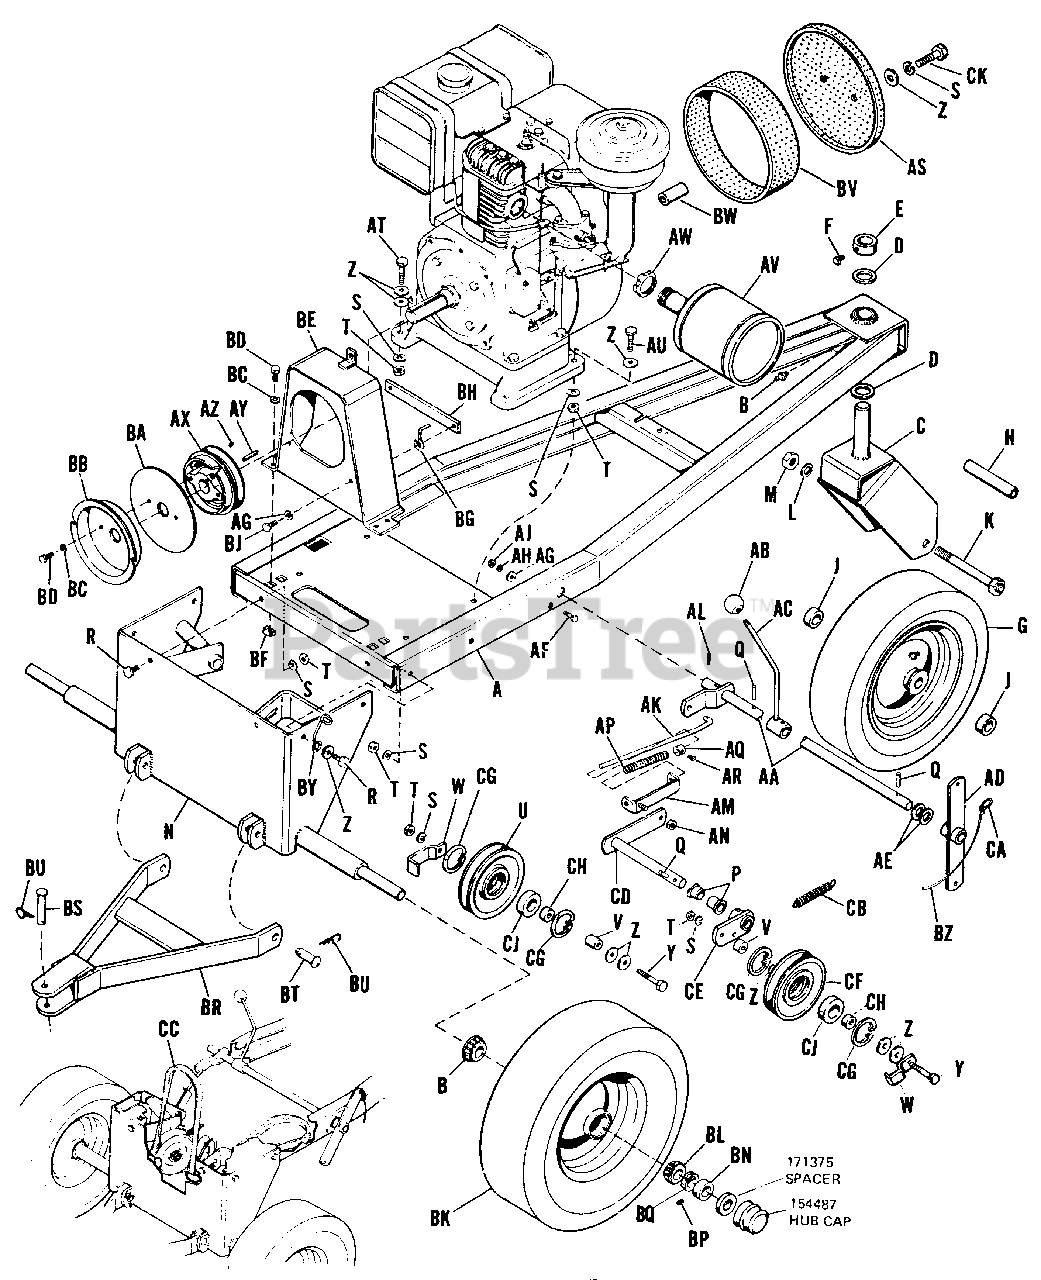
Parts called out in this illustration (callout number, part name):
A	Frame Assembly
B	Crease Fitting
C	Caster Assembly
E	Set Collar
F	Set Screw 5/16-18 x 1/2" lg.
G	Wheel & Tire Assembly
H	Spacer Tube
K	Rear Axle Shaft
L	Lock Washer 1/2"
M	Hex Nut Full 1/2-13
N	Front Plate Assembly
P	Clutch Bushing
R	Hex Capscrew 3/8-16 x 3/4" lg.
S	Lock 3/8" Washer 3/8"
T	Hex Nut Full 3/8-16
U	Idle Pulley
W	Belt Guide
Y	Hex Capscrew 3/8-16 x 2" lg.
Z	Plain Washer 3/8"
AA	Lever Sub Assembly
AC	Handle Sub Assembly
AD	Lever Sub Assembly
AF	Hex Capscrew 1/4-20 x 3/4" lg.
AG	Plain Washer 1/4"
AH	Lock Washer 1/4"
AJ	Hex x Nut 1/4-16
AK	Clutch Rod
AL	Cotter Pin
AM	Rod Guide Assembly
AN	Hex Nut Full Lock 5/16-18"
AR	Set Screw 1/4-20 x 3/8" lg.
AS	Cover Screen
AT	Hex Capscrew 3/8-16-1-1/2" lg.
AU	Hex Capscrew 3/8-16-1-1/4" lg.
AX	Engine Pulley
AZ	Set Screw 5/16-18 x 1/9" lg.
BB	Rope Starter Pulley
BC	Lock Washer 5/16"
BD	Hex Capscrew 5/16-18 x 3/4" lg.
BE	Guard Assembly
BF	Retainer Nut
BG	Belt Stop
BH	Belt Stop Clamp
BJ	Hex Capscrew 5/16-18 x 5/8" lg.
BK	Wheel & Tire Assembly (Front)
BL	BEARING CUP
BN	Set Collar
BP	Set Screw 5/16-18 x 5/16" lg.
BR	Tie Bar Assembly
BU	Spring Clip
BV	Engine Pulley Screen
BY	Rope Guide
CA	Repair Link
CC	"V" Belt
CD	Clutch Lever Sub Assembly
CE	Lever Sub Assembly
CF	Idler Pulley (Fixed)
CG	Retaining Ring
CK	Hex Capscrew, 3/8"-16 x 2"
